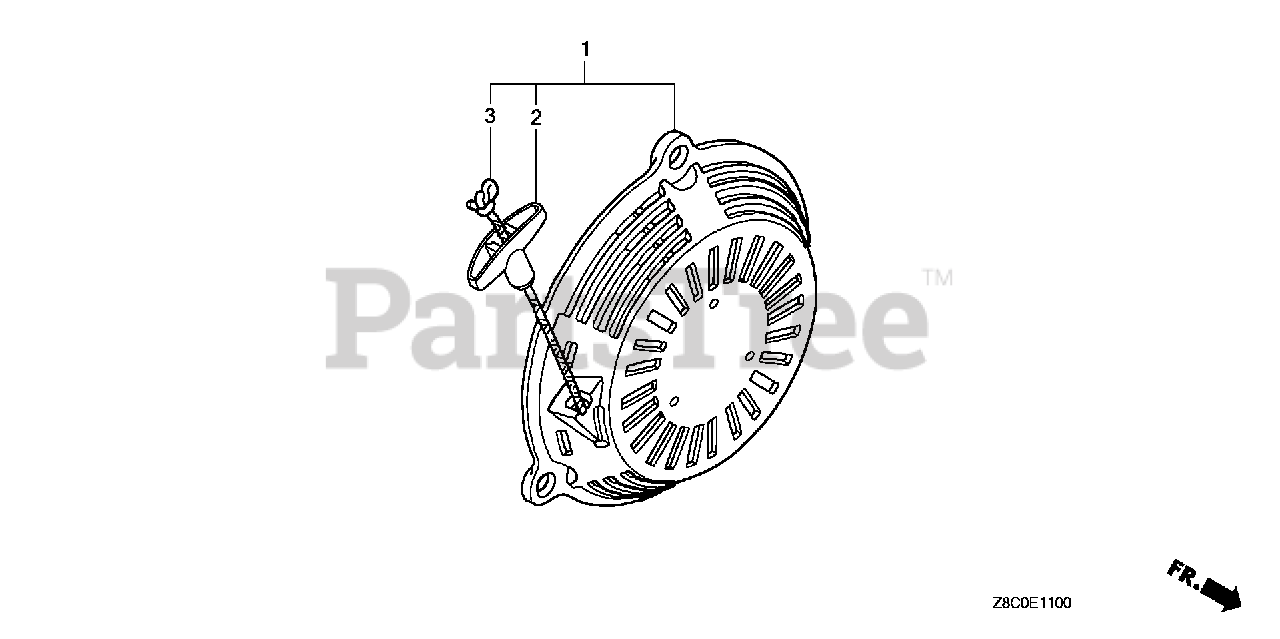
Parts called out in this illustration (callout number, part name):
1	STARTER ASSY., RECOIL *NH1* (BLACK)
1	STARTER ASSY., RECOIL *R280* (POWER RED)
2	GRIP, STARTER
3	ROPE, RECOIL STARTER
